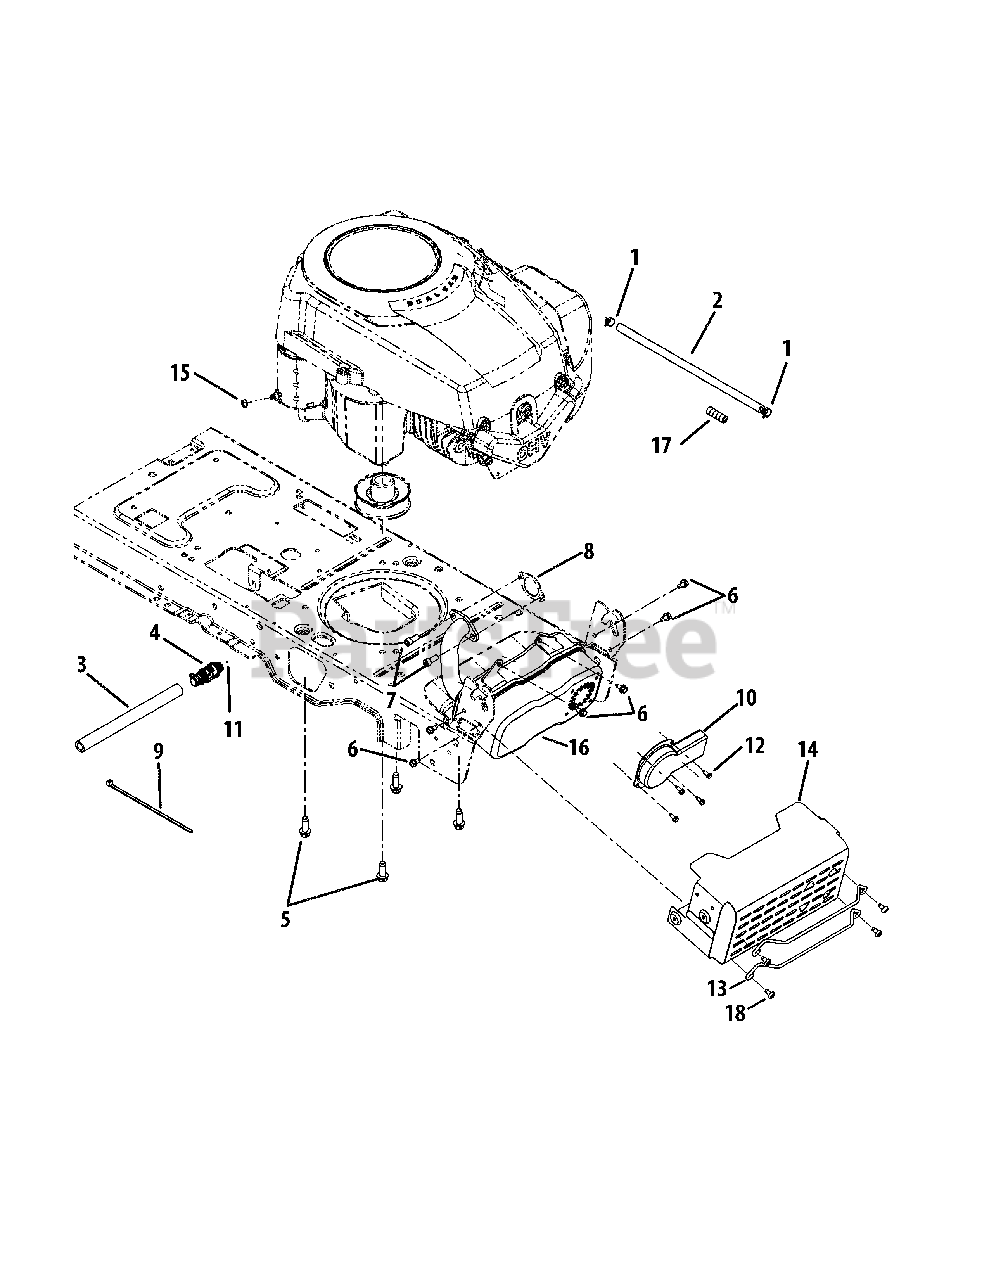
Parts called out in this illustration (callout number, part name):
1	Hose Clamp
2	Fuel Line 16" Lg.
3	Oil Drain Hose
4	Oil Drain
5	TT Screw 3/8-16 x 1.00
6	Hex Wash S-Tapp Scr 1/4-20 x .50
7	Scr. 5/16-18 x .75
8	Exhaust Gasket
9	Cable Tie
10	Long Muffler Deflector
11	Pipe Sealant
12	Hex AB Scr #8-18 x .50
13	Muffler Guard Rod
14	Muffler Shield Assembly
15	Hex Sems Nut 1/4-20
16	Muffler
17	Vent Hose
18	TT Pan Hd Scr. 1/4-20 x .50
